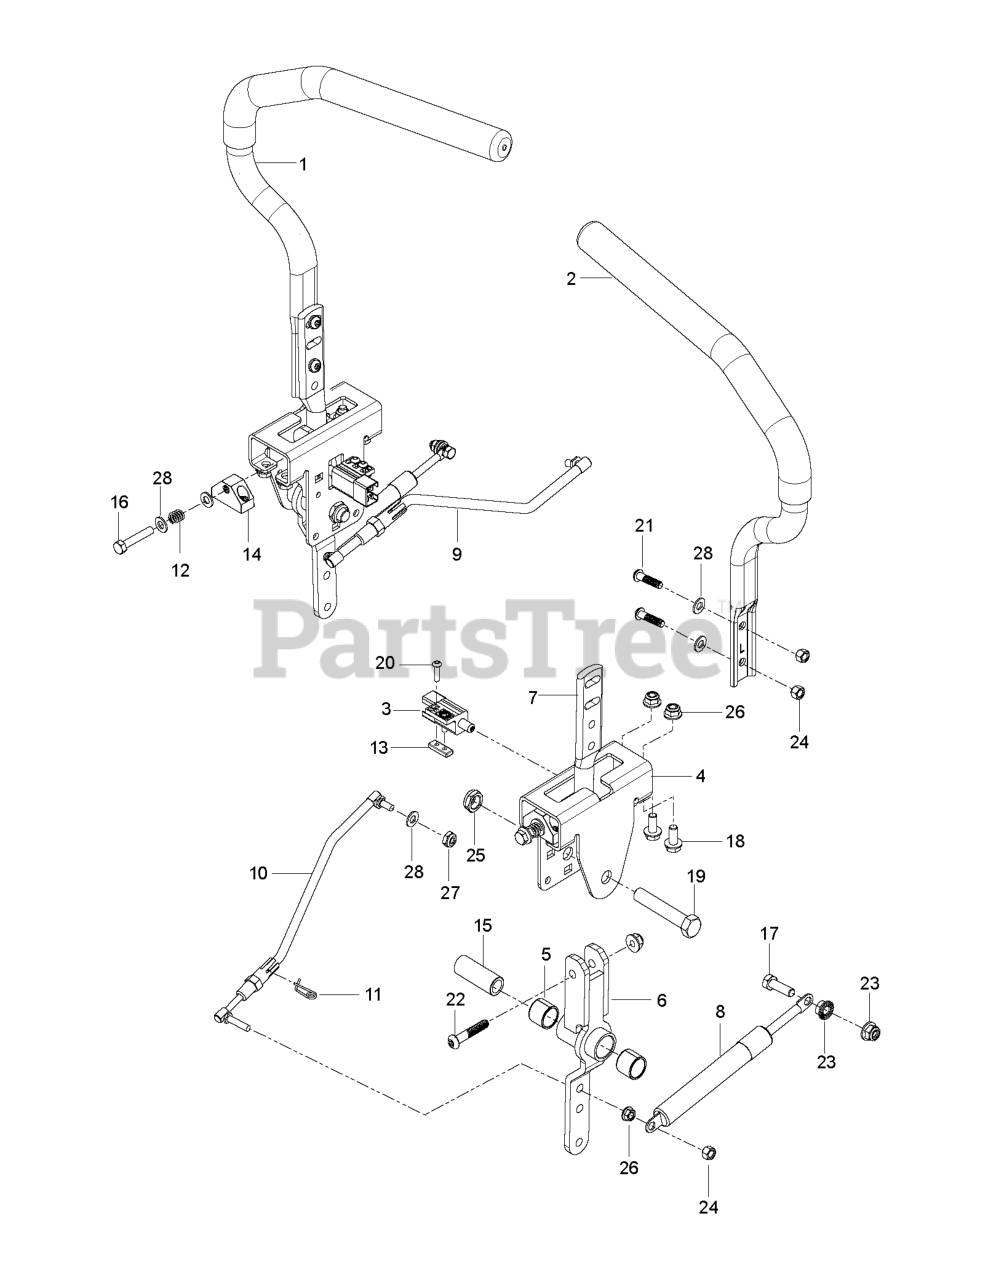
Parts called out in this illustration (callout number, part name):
1	TUBE.LEVER.CONTROL.ZTR.RT.428
2	TUBE.LEVER.CONTROL.ZTR.LT.428
3	SWITCH INTERLOCKT
4	BRACKET.CONTROLS.ZTR.X431
5	BEARING.PT.750
6	CONTROL.WELDMENT.RZ
7	LEVER.HANDLE MOUNT
8	DAMPENER
9	ROD.ASM.RH.ADJUSTABLE
10	ROD.ASM.LH.ADJUSTABLE
11	RETAINER.CLIP.SPRING.S
13	PLATE NUT ZTR
14	BLOCK TRACKING CONTROL ZTR
15	SPACER.PIVOT.CONTROL
16	CAPSCREW 5/16 X 1/1/2 HEX HEAD
17	HCS 5/16C X 1
18	HHFS 5/16-18 X 3/4
19	HCS 1/2-13 X 2-3/4 GD 5 ZD
20	SCR #10-24 X .75 SKT HD BLK
21	SCREW.BUTTHEAD.5/16-18X1-1.25
22	SCREW.CAP.SOCKET.6PT.5/16-18
23	NUT 5/16C WHIZ
24	NUT.71038.31-18.HEX.NYLOCK
25	NUT 1/2-13 HEX JM NYL
26	5/16-18 NYLOC FLANGE NUT
27	5/16-18 THIN PROF NY
28	WASHER
